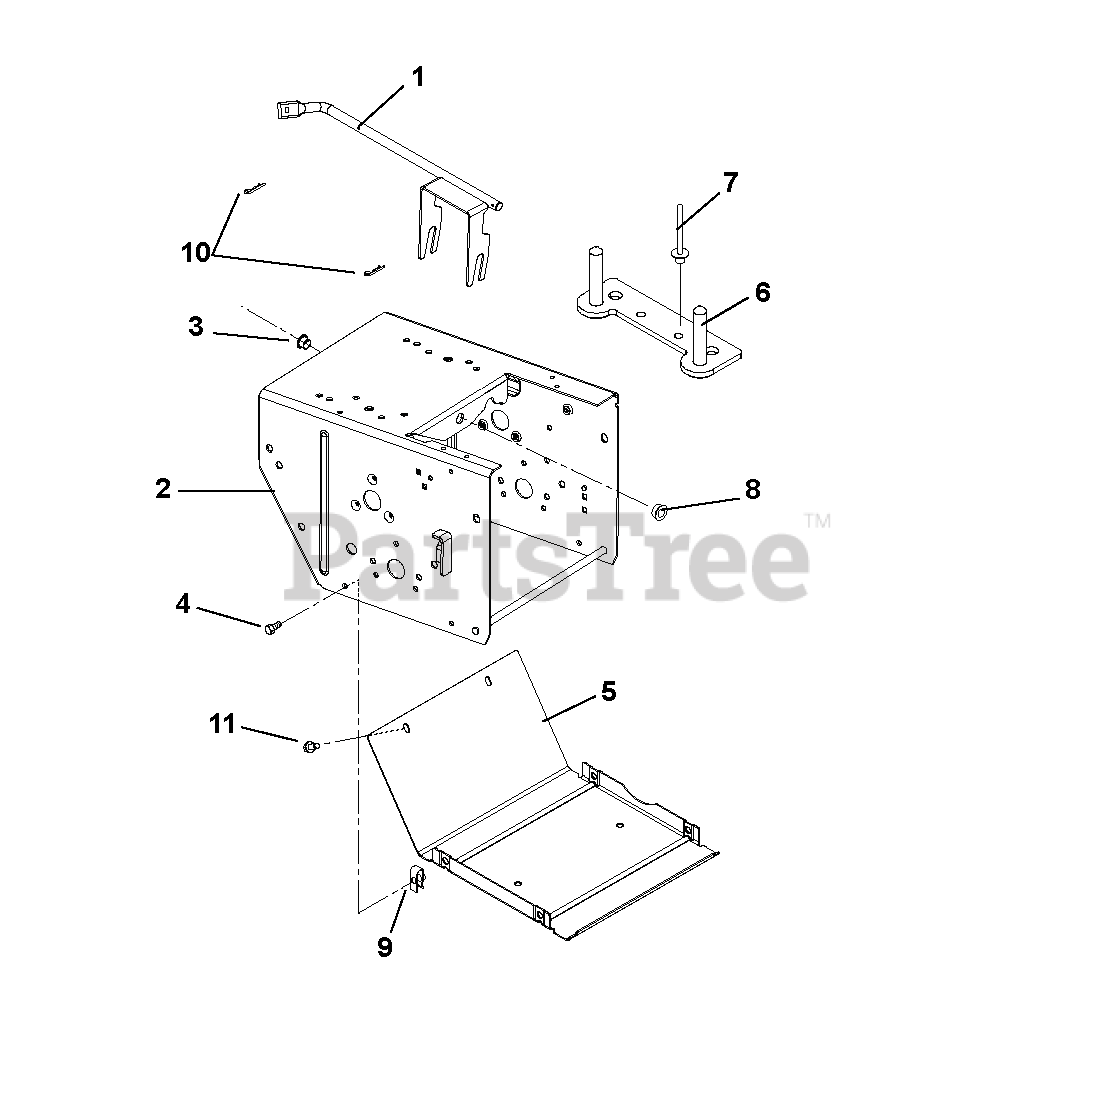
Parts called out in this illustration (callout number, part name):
1	ARM, SHIFT-WELDMENT
2	PRO HYDRO FRAME, MAIN
3	BUSHING, POLYLINER-.50 SPLIT
4	BLT-HEX .25-20X.75 HWH YZ GR5
5	COVER, BOTTOM
6	STRAP, ENGINE BOLT-LARGE BRIGG
7	RVT-POP .187 YZ
8	BUSHING, POLYLINER-.50 SNAPIN
9	NUT-RTNR .25-20X.56
10	CLIP, SPRING
11	SCR-TAP .25-20X.50 HWH TR YWZ
